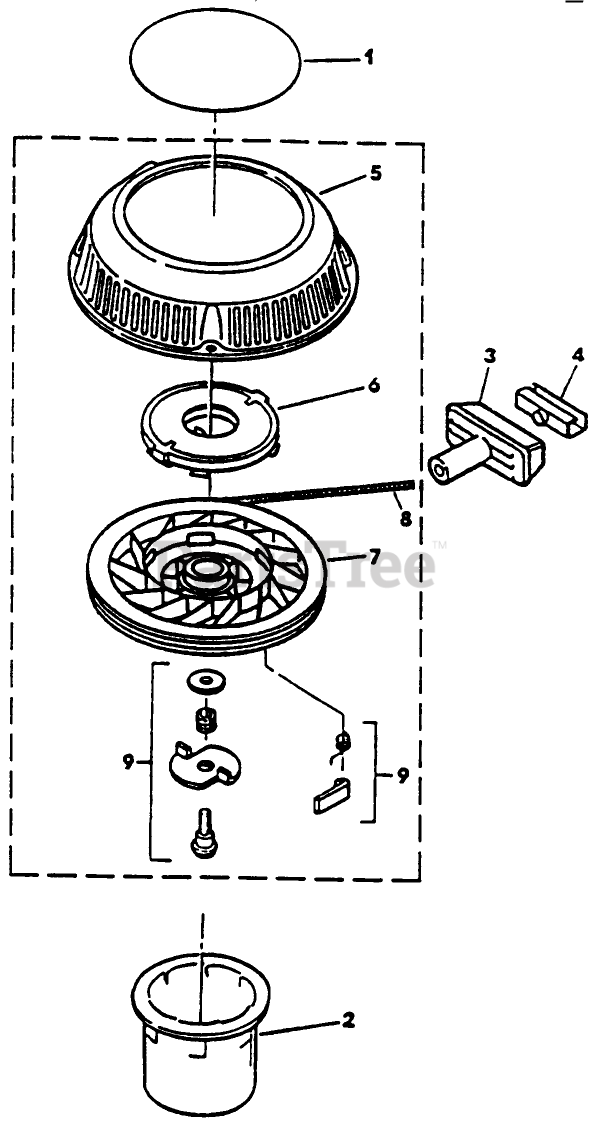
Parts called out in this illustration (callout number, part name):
2	HUB-STARTER E COMM.
4	CLIP-STARTER
5	STARTER HOUSING & SHAFT
7	PULLEY
9	DOG KIT
